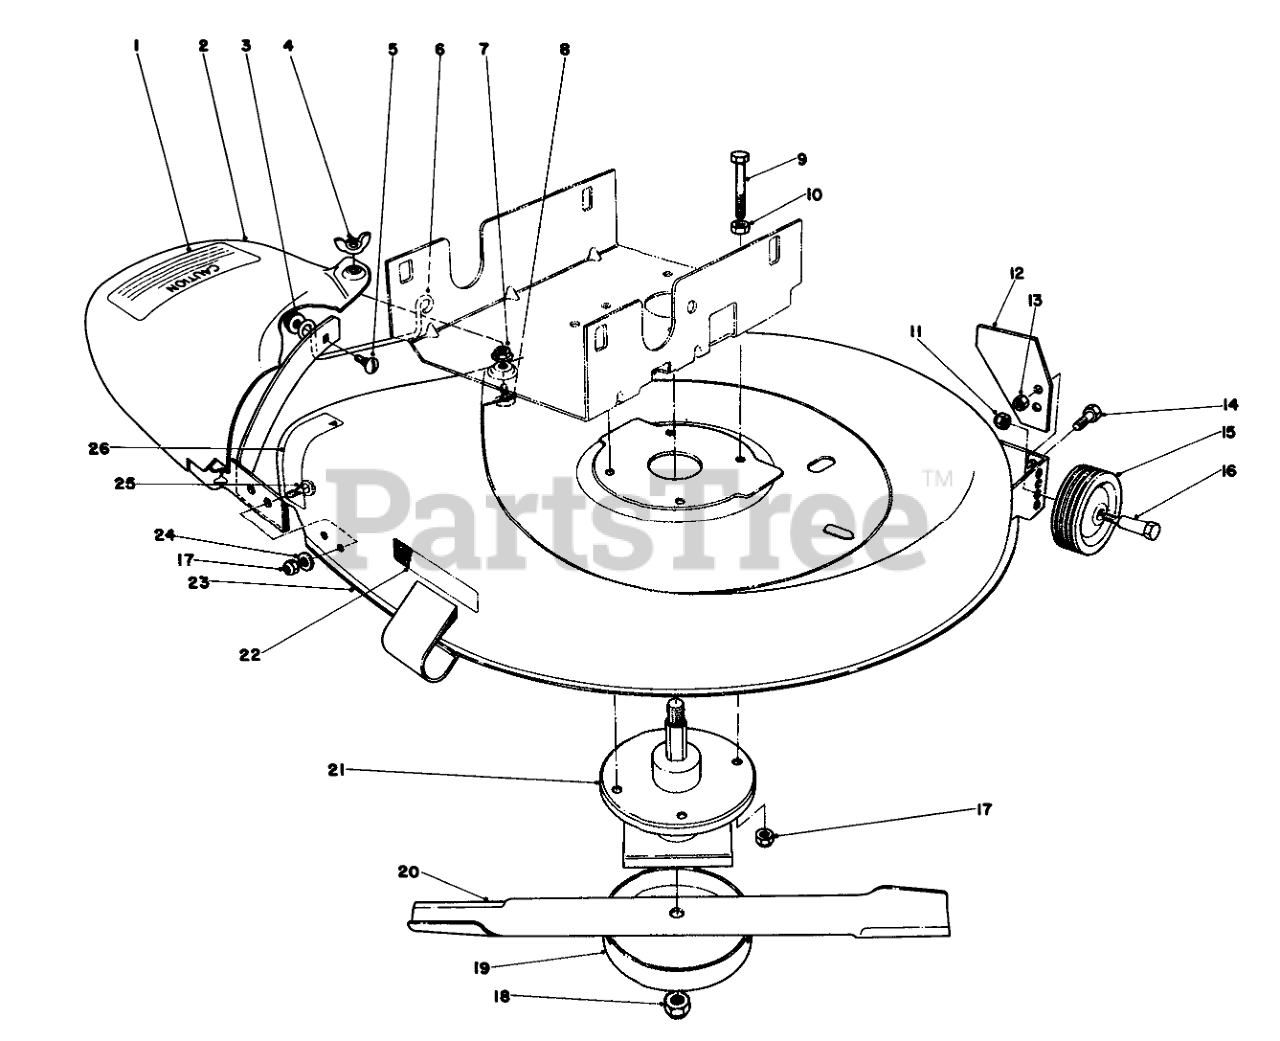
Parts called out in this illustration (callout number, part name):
1	Decal
2	DEFLECTOR WA R
3	NUT-LOCK, HHF
4	Wing Nut
5	SCREW-CARRIAGE
6	Bracket Foot Guard
7	PAL NUT
8	Carriage Bolt
9	SCREW-HH
10	NUT-JAM
11	Nut
12	Deck Stop
13	NUT-LOCK, CONE
14	SCREW-HH
15	Wheel
17	NUT-LOCK, CONE
19	Cup
20	Blade
21	Mower Spindle
22	Decal-Deck Inst.
23	HOUSING WA R
24	WASHER-FLAT
25	BOLT-CARR
26	Decal Housing
